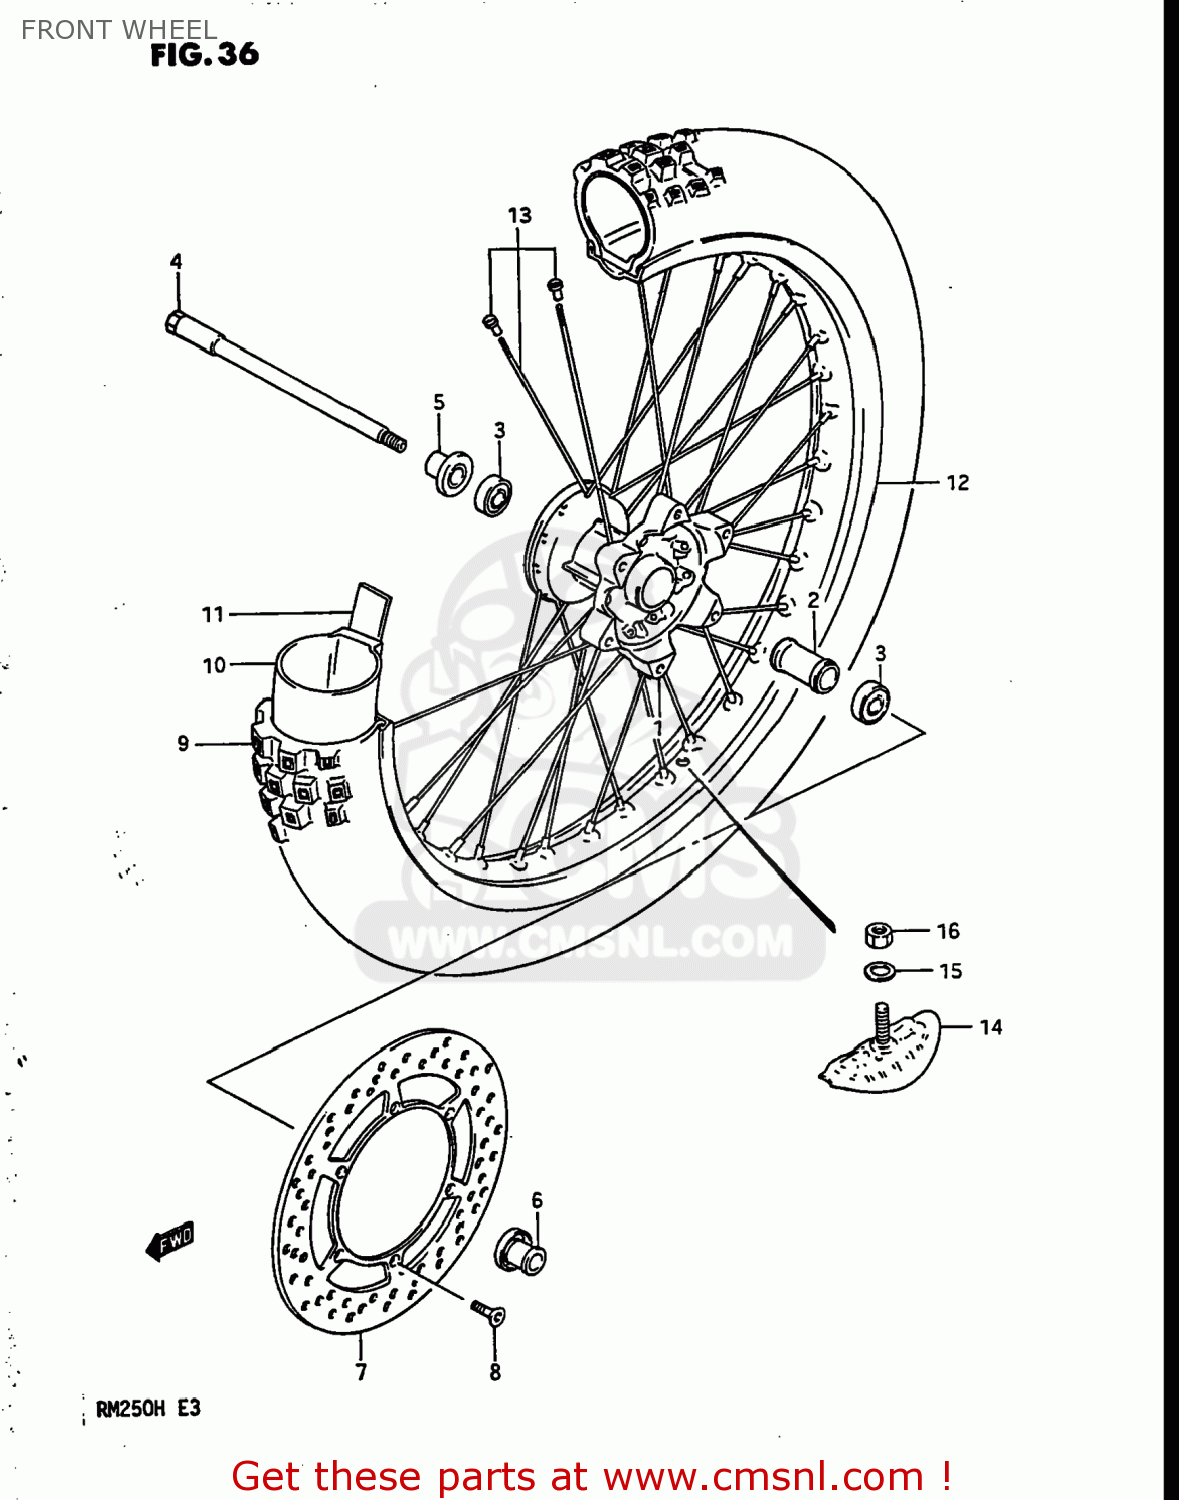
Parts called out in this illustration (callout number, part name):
1	HUB,FRONT
2	SPACER,FR HUB BEARING
3	BEARING
4	AXLE,FRONT
5	SPACER,FRONT AXLE,RIGHT
6	SPACER,FRONT AXLE,LEFT
7	DISC,BRAKE
8	SCREW
9	TIRE,FRONT
10	TUBE
11	PROTECTOR,WHEEL,INNER
12	RIM,FRONT WHEEL
13	SPOKE SET,FRONT
14	STOPPER,BEAD
15	WASHER
16	NUT 8MM
